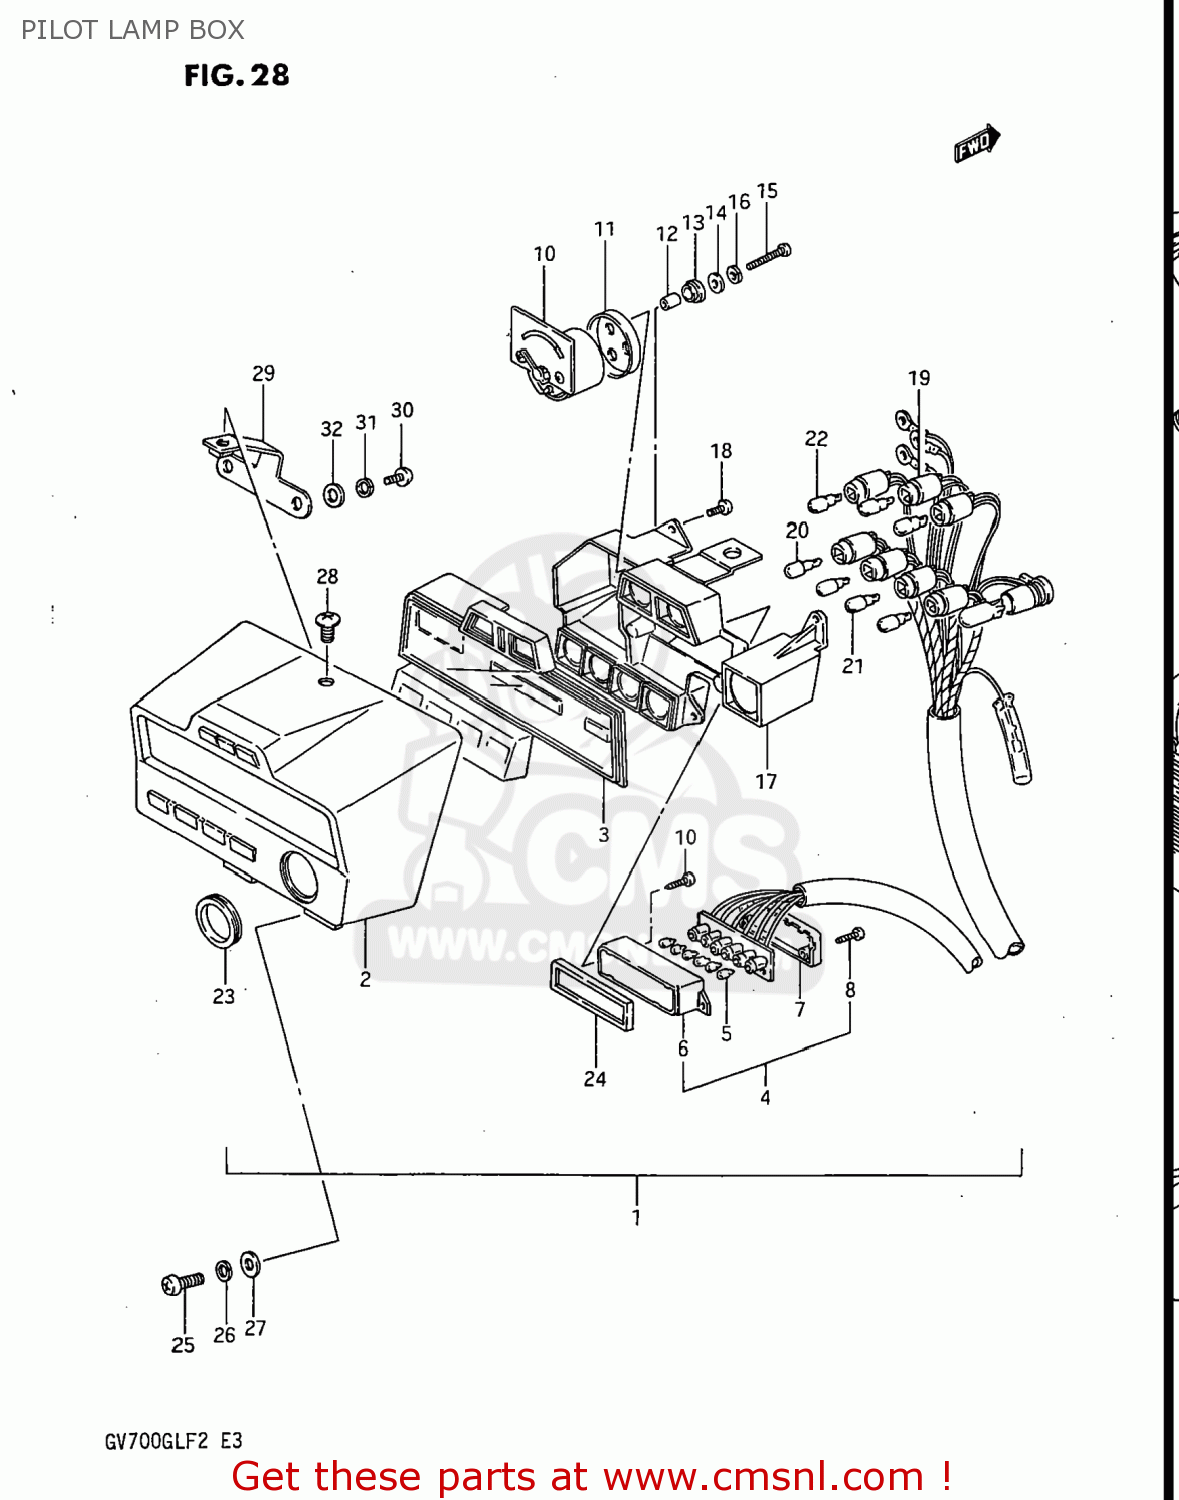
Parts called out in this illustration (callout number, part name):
1	BOX ASSEMBLY,PILOT LAMP
2	COVER SET,PILOT BOX
3	COVER SET,PILOT BOX
4	INDICATOR,GEAR POSITION
5	BULB(14V1.12W)
6	CASE,GEAR INDICATOR
7	COVER,LWR
8	SCREW,GEAR INDICATOR
9	SCREW,INDICATOR
10	METER,WATER TEMPERATURE
11	PAD
14	WASHER,FUEL METER
15	SCREW
16	LOCK WASHER
17	CASE,PILOT BOX,LOWER
18	SCREW
19	SOCKET,PILOT LAMP
20	BULB(12V3W,T6.5)
21	BULB(12V1.7W,T6.5)
22	BULB(12V3.4W,T10)
23	CUSHION
24	GASKET
25	SCREW
26	WASHER,LOCK
27	WASHER
28	SCREW 6X12
30	SCREW
31	WASHER,LOCK
32	WASHER,5MM
